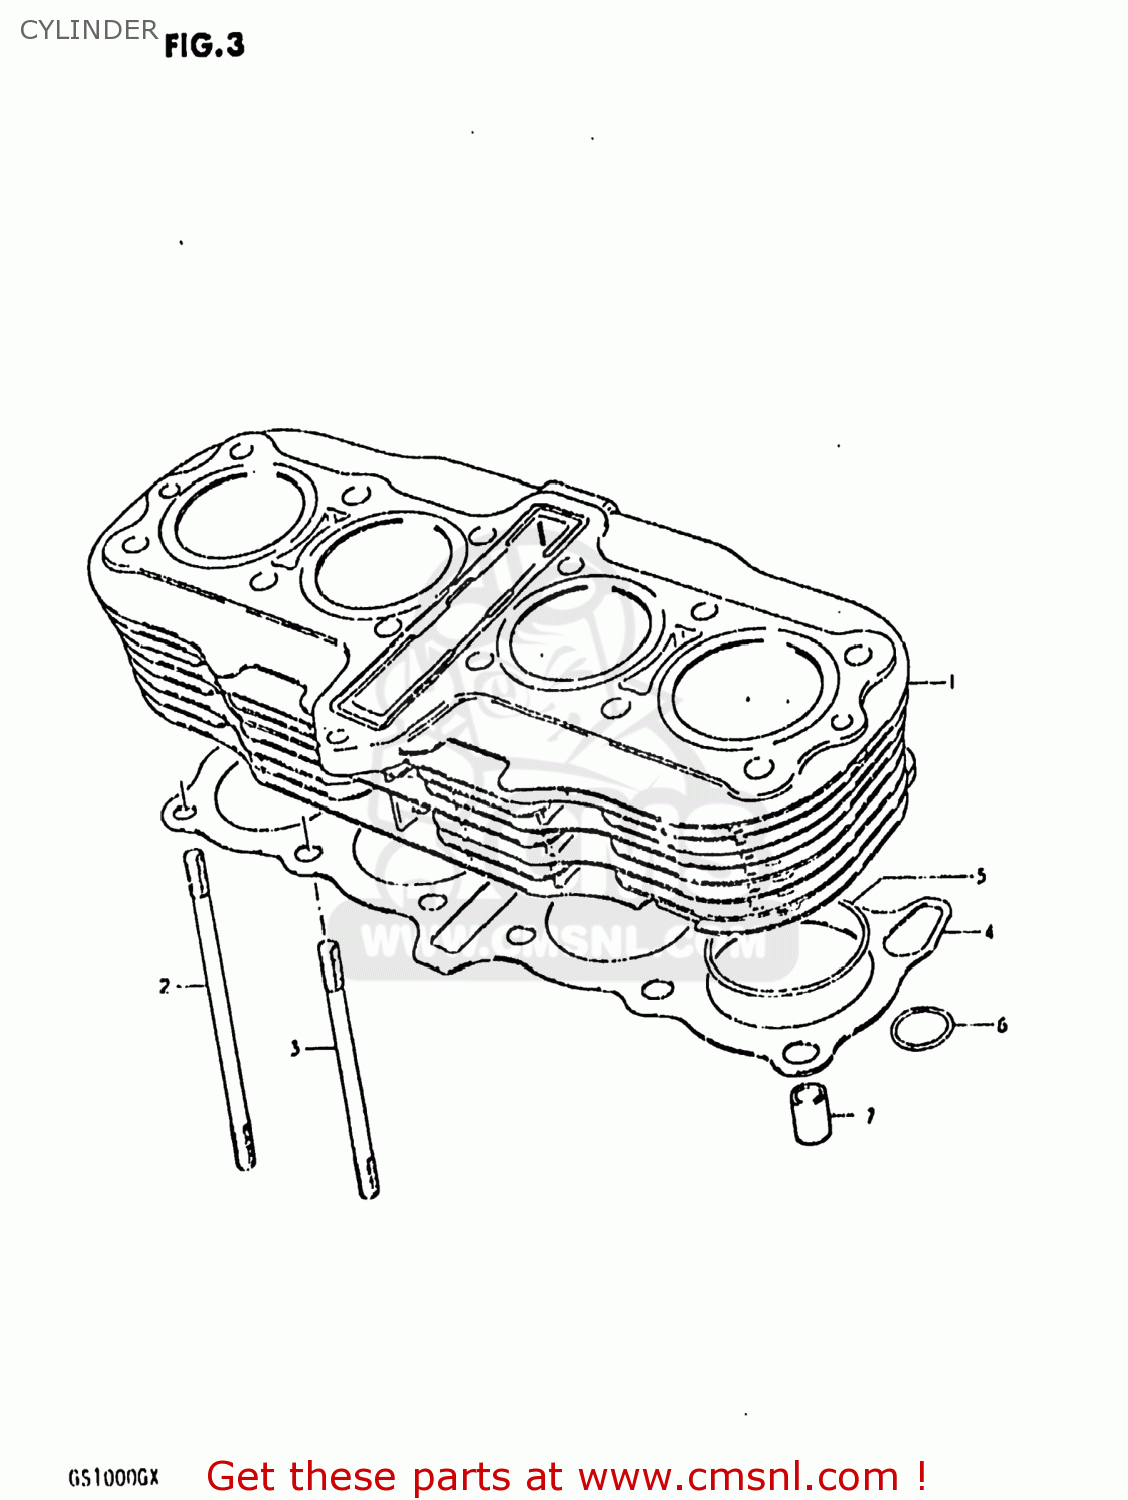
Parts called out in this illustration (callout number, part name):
1	CYLINDER
2	BOLT,STUD
3	STUD
4	GASKET,CYLINDER (MCA)
5	O RING(D:2,ID:74)
6	O RING(D:3.05)
7	PIN
